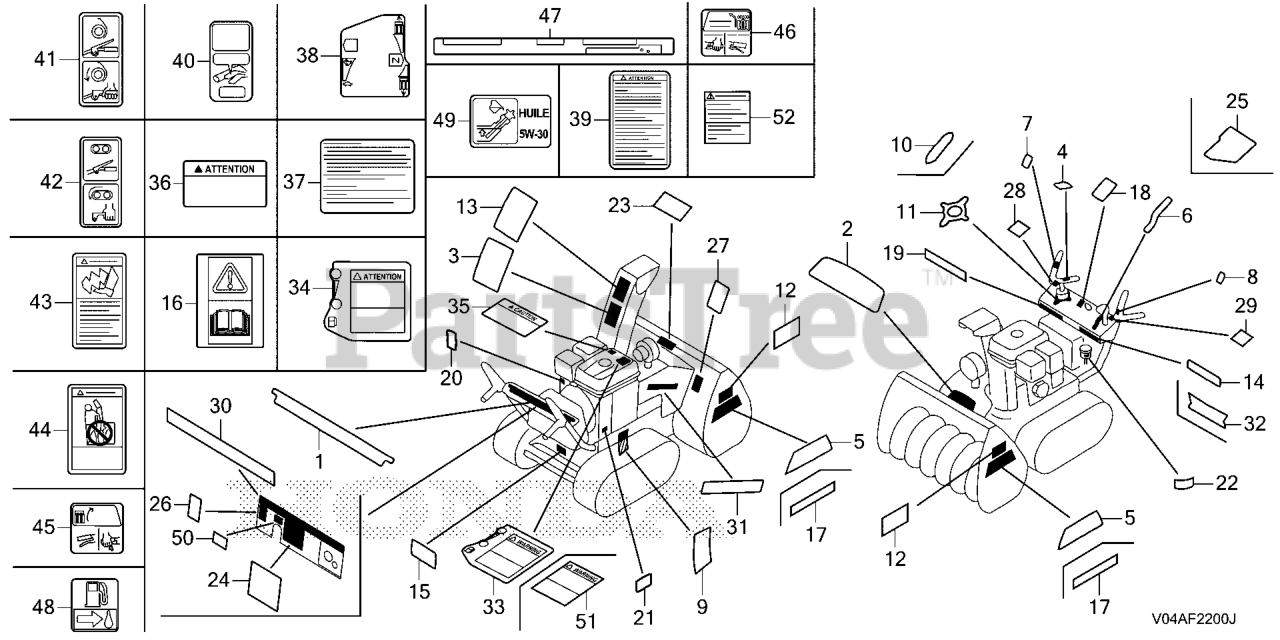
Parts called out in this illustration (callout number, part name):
2	MARK, EMBLEM (HSS724A)
3	LABEL, WARNING (E)
7	MARK, AUGER CLUTCH (A)
8	MARK, CLUTCH (A)
11	MARK, CHUTE OPERATION (Z)
13	MARK, DISCHARGE DANGER (E)
20	MARK, FUEL INDICATION (A)
21	MARK, OIL CAUTION (E)
21	MARK, OIL CAUTION
24	LABEL, OPERATION (DC START-E) (NA USE ALT:87110-V45-A11)
24	LABEL, OPERATION (DC START-E)
25	MARK, CHANGE (E)
26	MARK, HEIGHT ADJUSTING (E)
27	MARK, DANGER (E)
28	MARK, R. TURN (E)
29	MARK, L. TURN (E)
30	MARK, ENGINE SWITCH (DC START-E)
31	MARK, HONDA
32	MARK, HONDA (B)
33	MARK, FUEL WARNING COMBINATION (ENGLISH)
35	MARK, EX. CAUTION (ENGLISH)
